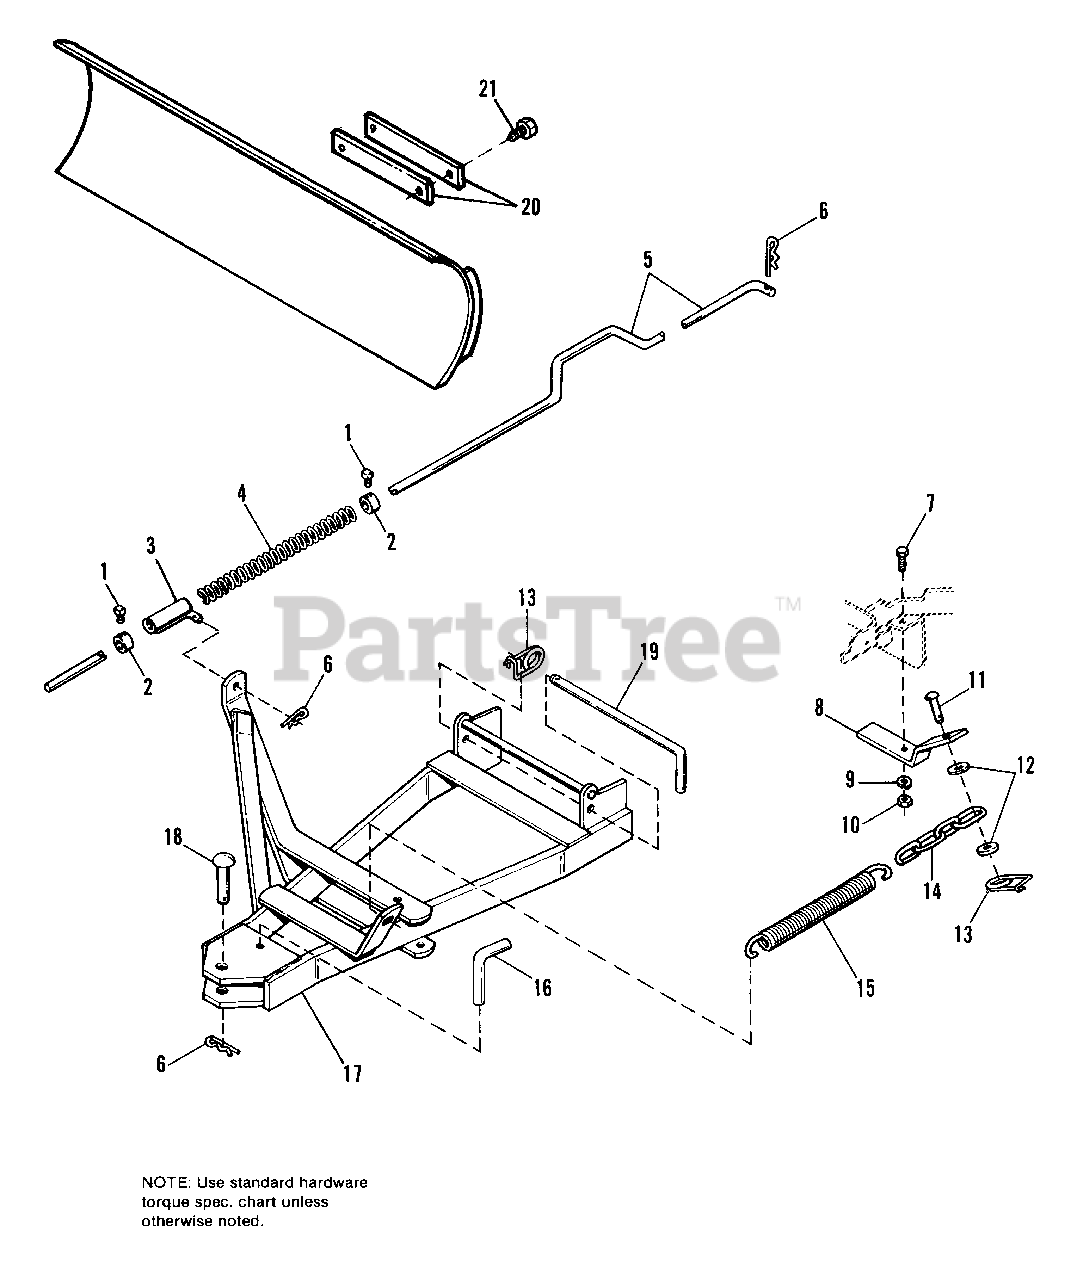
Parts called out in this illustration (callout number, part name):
1	SETSCREW, 5/16-18 x 1/2
2	COLLAR, Set
3	GUIDE ASSY, Rod
5	ROD, Lift (Mfg. No. 1691833 Only)
5	ROD, Lift (Mfg. No. 1692039 Only)
6	CLIP, Spring
7	CAPSCREW, Hex, 5/16-18 x 1
8	BRACKET, Spring Anchor
9	LOCKWASHER, 5/16
10	NUT, Hex, Full, 5/16-18
11	PIN, Hitch
12	WASHER, Plain, 5/16
13	CLIP, Safety
14	CHAIN, 4-Link
17	PUSH BAR ASSY.
20	BAR STOP.(Mfg. No. 1692039 Only)
21	SCREW, Hex, Taptite, 5/16-18 x 1 (Mfg. No. 1692039 Only)
